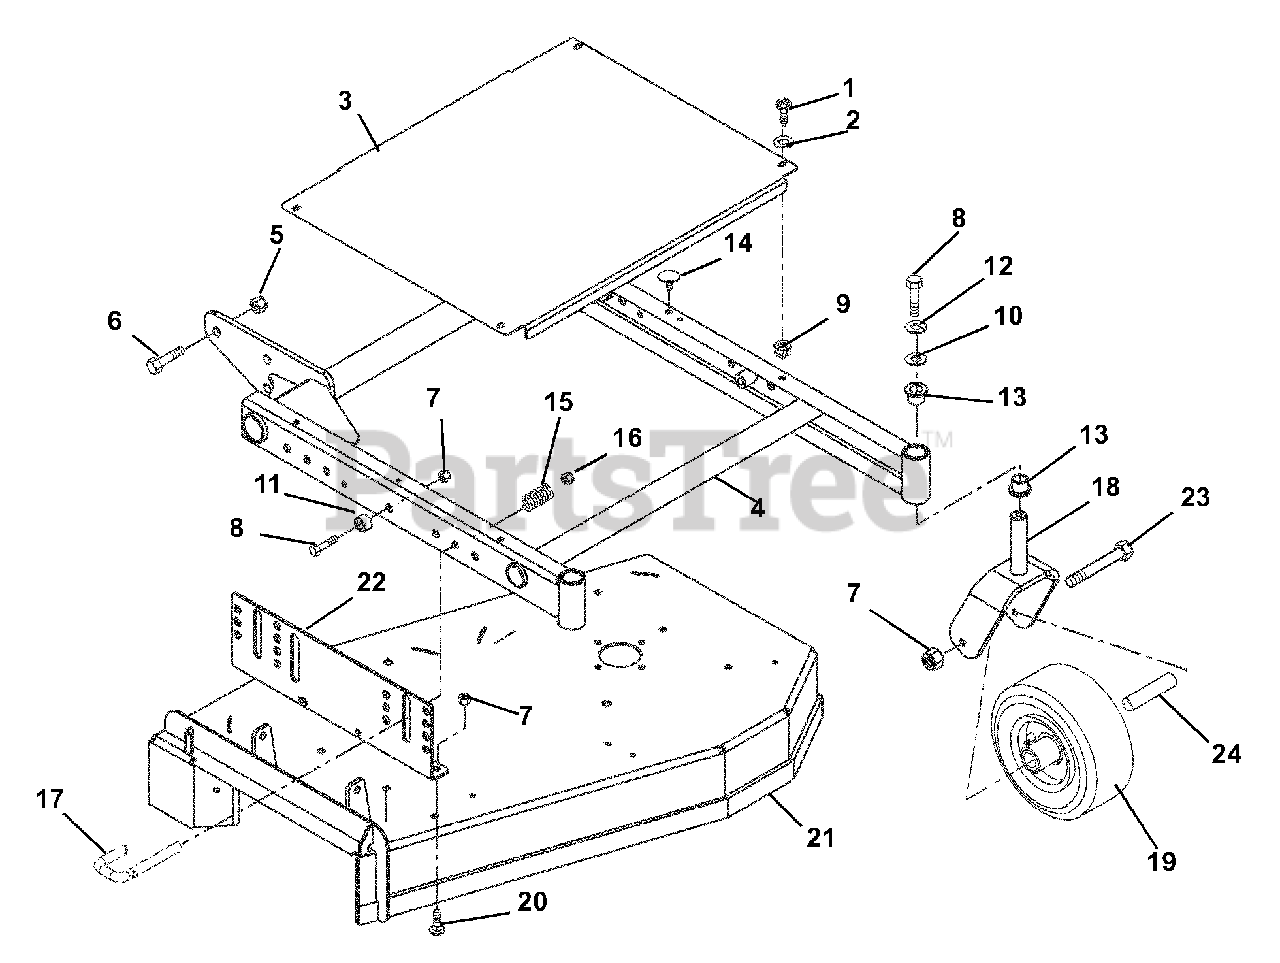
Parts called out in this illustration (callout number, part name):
1	@SCR-TAP .25-20X.50 HWH TR YWZ
2	@WSHR-FL-STL.281X.62X.065 YWZC
3	COVER - BELT - PRO - 32"
4	WMT - MOWER FRAME - 32"
5	@NUT-LK-NYL .625-11 YWZC
6	@BLT-HEX .62-11X1.50 GR5 YWZC
7	@NUT-LK-TOP-FLG .38-16 YWZC
8	@BLT-HEX .38-16X1.25 GR5 YWZC
9	GRMT,PLASTIC
10	WSHR-FL-STL .380X1.50X.125YWZC
11	BSHG-SLV .391X.688X.52 PM
12	@WSHR-LK .38X.094 REG YWZC
13	BSHG-FLG 1.00X1.25X1.50X1.50EP
14	BUMPER GROMMET
15	SPRG, COMP .058X.65X2.13 WLD15
16	@NUT-LK-CTR .50-13 YWZC
17	PIN - LATCH
18	WMT - CASTER FORK
19	WHEEL 9 X 3.50 SEMI-PNEUMATIC
20	@BLT-RDHDSQNK .38-16X1.00 G5YZ
21	KIT-32" FX MOWER DECK W/DECALS
22	KIT-MOWER SIDE SUPT BRKT-RH&LH
23	BLT-HEX .38-16X5.50 YWZC
24	BEARING .625 X .380 X 4.08
